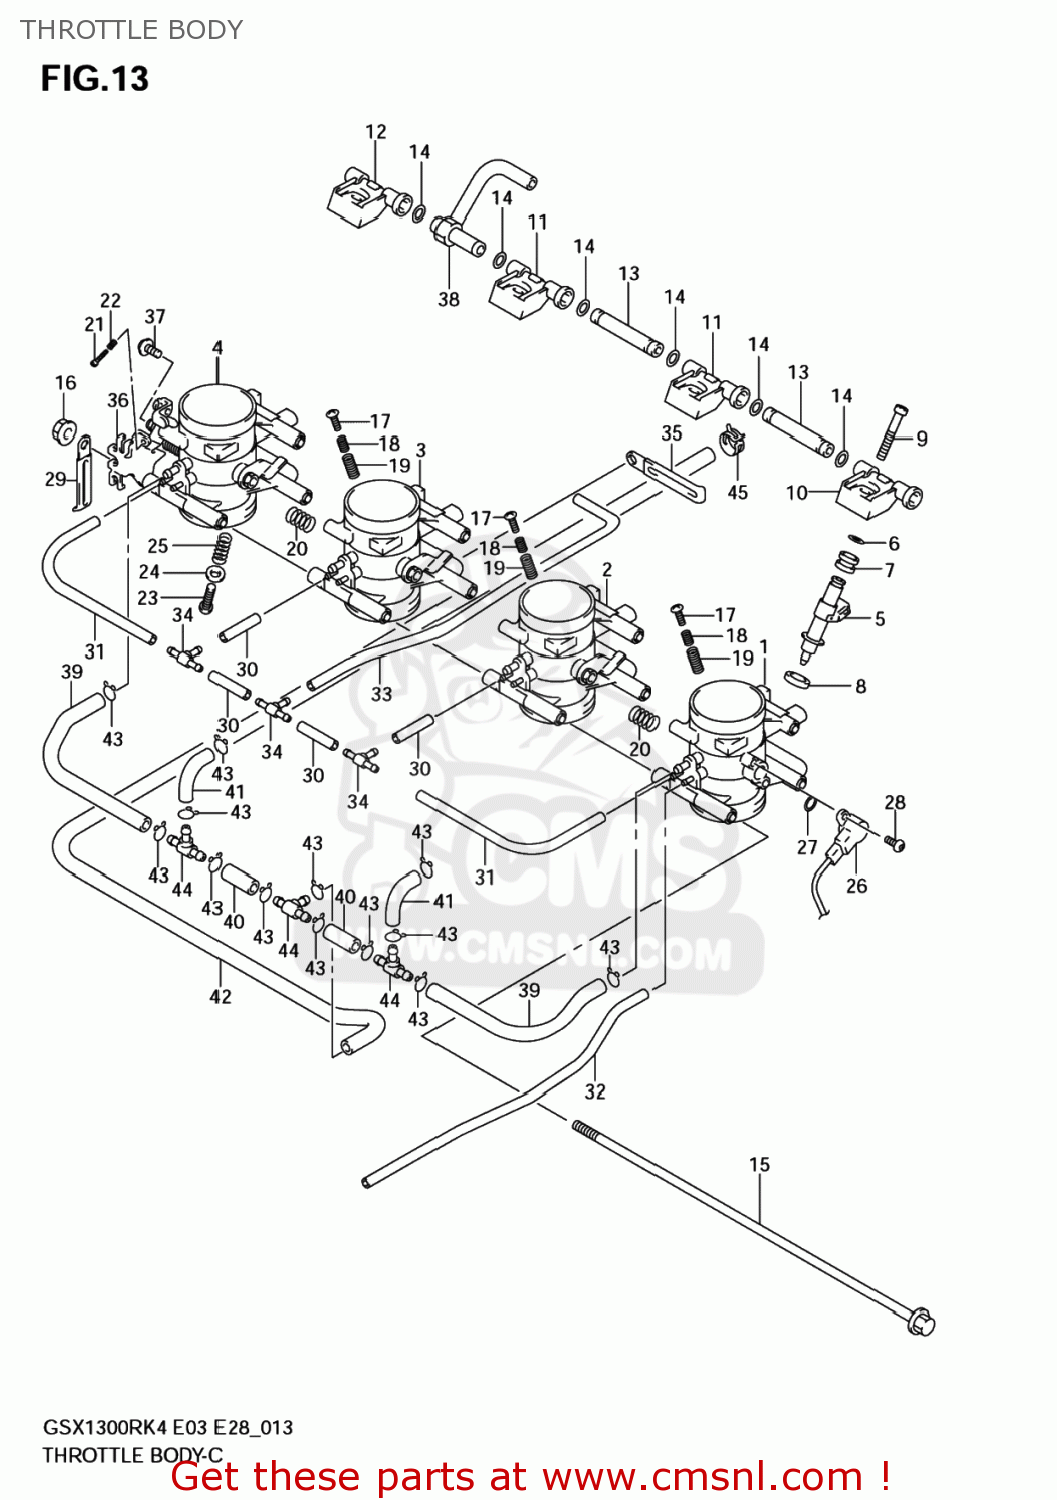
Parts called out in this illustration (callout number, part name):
1	THROTTLE BODY ASSY,L
2	THROTTLE BODY ASSY ML
3	THROTTLE BODY ASSY MR
4	THROTTLE BODY ASSY,R
5	INJECTOR ASSY
6	O RING
7	RING,CUSHION
8	RING,SEAL
9	SCREW
10	JOINT,NO.1
11	JOINT,NO.2,3
12	JOINT,NO.4
13	JOINT
14	O RING
15	BOLT
16	NUT
17	SCREW,STOP
18	SPRING
19	SPRING
20	SPRING
21	SCREW
22	SPRING
23	SCREW,STOP
24	WASHER
25	SPRING
26	SENSOR ASSY,TH
27	O RING
28	SCREW
29	CLAMP
30	HOSE,RUBBER(L:35)
31	HOSE,RUBBER(L:100)
32	HOSE,RUBBER(L:200)
33	HOSE,RUBBER(L:230+20)
34	JOINT
35	BAND
36	PLATE,STAY
37	SCREW
38	JOINT
39	HOSE,RUBBER(L:80+25)
40	HOSE,RUBBER(L:35)
41	HOSE,RUBBER(L:30+30)
42	HOSE,RUBBER(L:440+30)
43	CLIP
44	JOINT
45	CLIP
